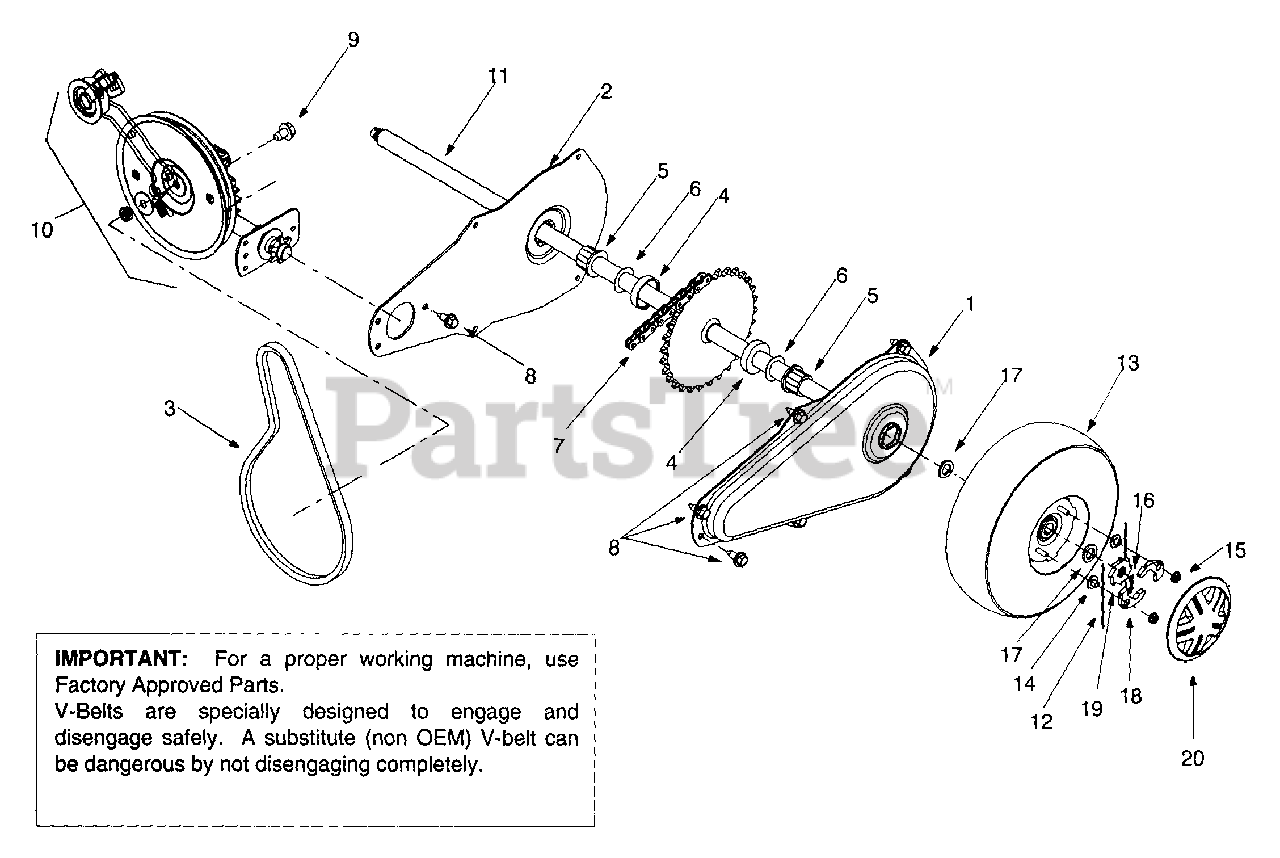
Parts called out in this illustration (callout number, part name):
3	V-Belt
4	Spacer
5	Hex Flange Bearing
6	Flat Washer
7	Chain
8	Hex Washer Screw 1/4-14
9	Hex Washer Screw 5/16
10	Transmission Asm
11	Axle Asm
12	Plastic Spring Ratchet
13	Wheel Complete 10 x 4 x 4
13	Pneumatic Tire 10.0 x 4.0
13	Valve
13	Flange Bearing .632 ID
14	Hex Nut 1/4-20
15	Hex Flanged Lock Nut 1/4-20
16	Cotter Pin
17	Flat Washer 5/8 ID x 1.0 OD
18	Pawl LH .345 ID
18	Pawl RH .345 ID
19	Wheel Ratchet 1.62 OD x .5 serr
20	Hubcap
